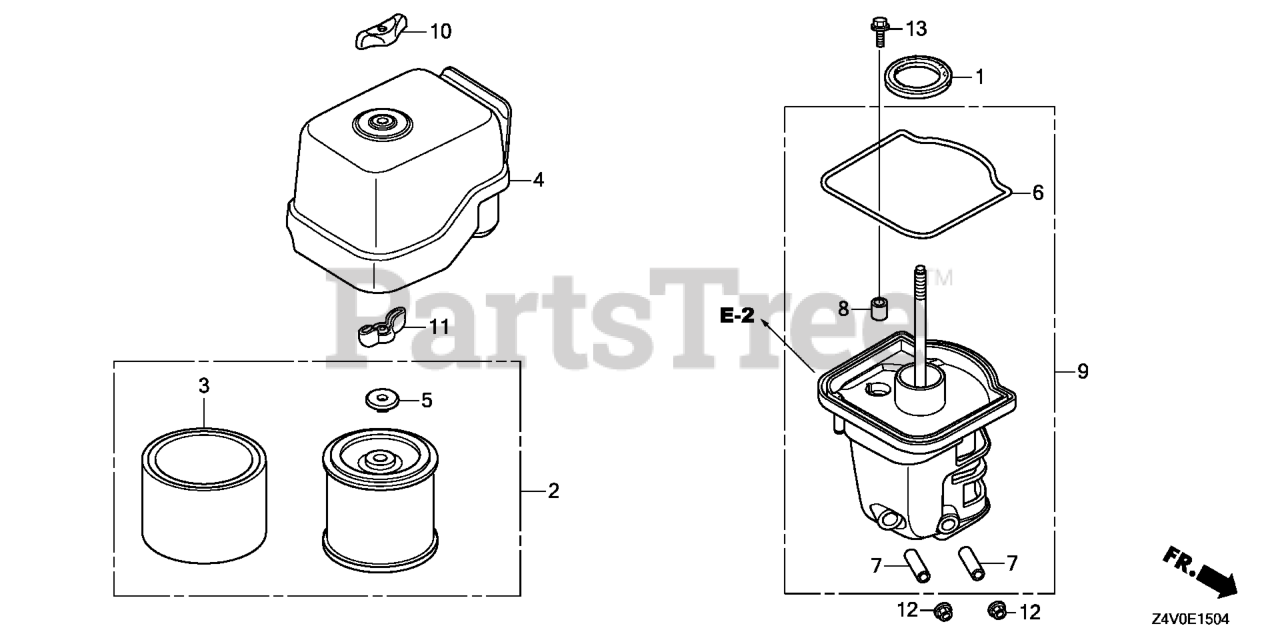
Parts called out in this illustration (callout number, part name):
1	GASKET, ELBOW
2	ELEMENT, AIR CLEANER
3	FILTER (OUTER)
4	COVER ASSY., AIR CLEANER
5	GROMMET, AIR CLEANER
6	SEAL, AIR CLEANER COVER
7	COLLAR, AIR CLEANER Use from Engine SN 1786085.
8	COLLAR B, AIR CLEANER
9	ELBOW, AIR CLEANER
10	NUT, AIR CLEANER
11	WINGNUT, TOOL BOX SETTING
12	NUT, FLANGE (6MM)
13	BOLT, FLANGE (6X20)
